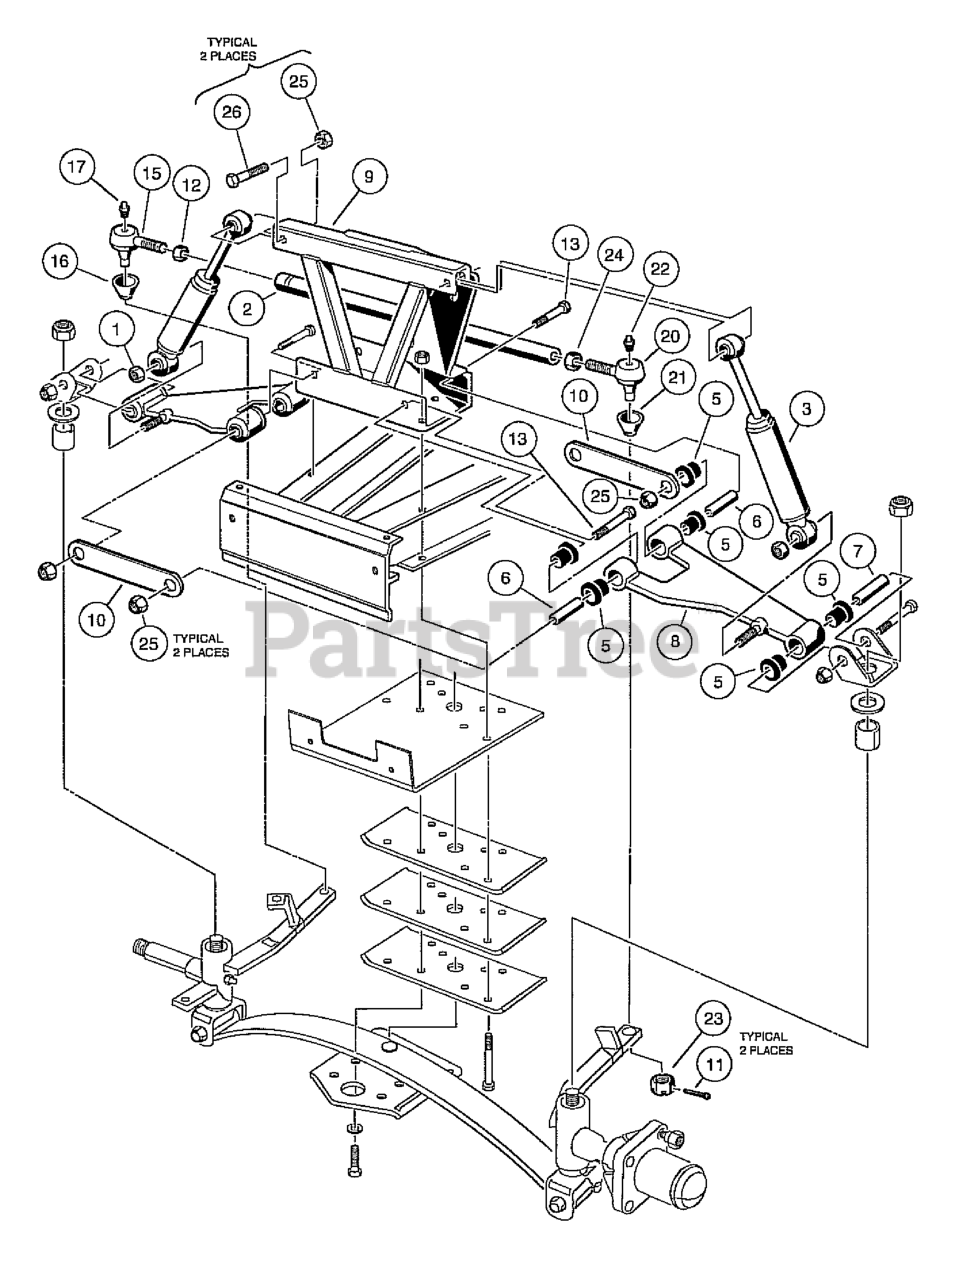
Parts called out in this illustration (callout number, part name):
1	LOCKNUT, DIMPLED
2	TIE ROD PLATING
3	SHOCK ABSORBER, FRONT COMMON
4	DELTA A PLATE SUB ASSEMBLY
5	BUSHING, URETHANE
6	SLEEVE, DELTA INNER
7	SLEEVE, DELTA OUTER
8	Detla A-Plate
9	ASM, DELTA SHOCK & GEAR SUPPOR
10	A PLATE STRAP
11	PIN,CUT COTTER
12	NUT, 1/2-20 HEX
13	SCREW, 3/8-16 X 2.25 HX HD CAP
14	BALL JOINT, RH
15	BALL JOINT, RH
16	SEAL, VERTICAL SOCKET DUST
17	FITTING, 1/4-28 THRD FRM GREAS
18	NUT, 3/8-24 UNF HEX THICK SLOT
19	BALL JOINT, LH
20	BALL JOINT, LH
21	SEAL, VERTICAL SOCKET DUST
22	FITTING, 1/4-28 THRD FRM GREAS
23	NUT, 3/8-24 UNF HEX THICK SLOT
24	NUT, 1/2-20 HEX
25	LOCKNUT, 3/8-16 HEX
26	BOLT, 3/8-16 X 1.75 HEX
